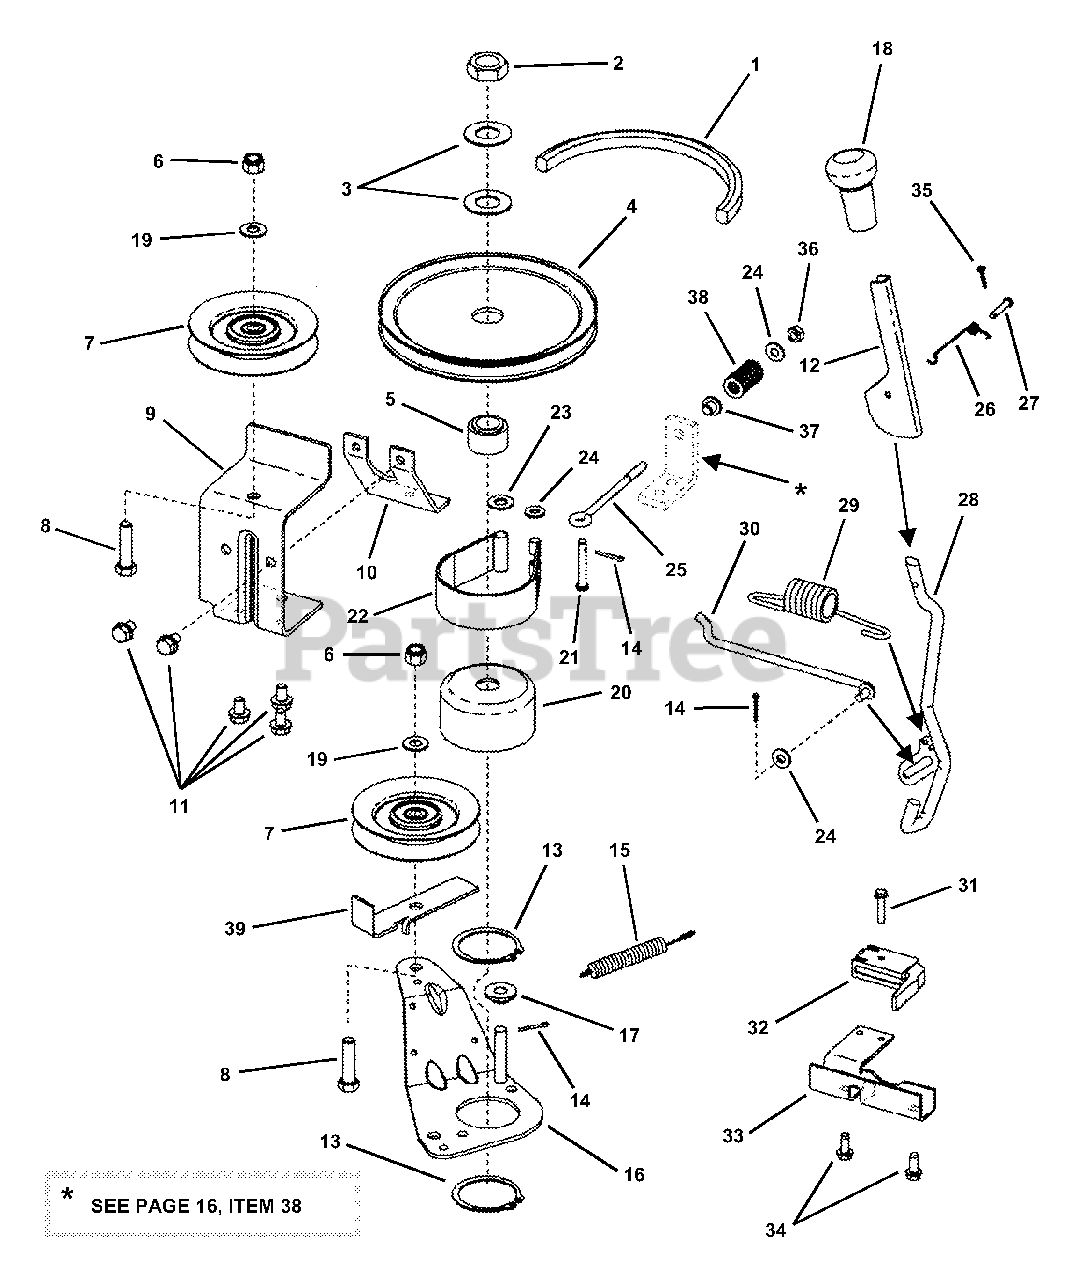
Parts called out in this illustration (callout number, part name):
1	BELT, Drive, (33" Deck) (73.75" AA Section)
2	NUT, 3/4-16 Hex Jam, Grade 8
3	WASHER, 49/64" I.D. x 1-1/2" O.D. Flat
4	PULLEY, Spindle
5	HUB, Pulley
6	NUT, 3/8-16 Nyloc
7	PULLEY, 4" Idler
8	SCREW, 3/8-16 x 1-1/2" Hex Head Cap, Grade 5
9	BRACKET, Fixed Idler (33" Models Only)
10	BRACE, Fixed Idler Bracket (33" Models Only)
11	SCREW, 5/16-18 x 1/2" Hex Washer Self-Tap
12	HANDLE, Blade Engage (Flip)
13	RING, 2" External Retaining
14	PIN, 3/32 x 3/4" Cotter
15	SPRING, Extension, 4" x 1/2" Diameter
16	ARM, Idler (weldment)
17	SPACER
18	GRIP, Handle
19	WASHER, 3/8" Flat
20	DRUM, Brake
21	PIN, 1/4" x 1-5/8" Clevis
22	BAND, Brake
23	WASHER, 3/8" Flat
24	WASHER, 1/4" Flat
25	EYE-BOLT, 1/4-20 x 4"
26	SPRING, Flip Handle
27	PIN, 3/16 x 1" Clevis
28	HANDLE, Blade Lever (ON-OFF)
29	SPRING, Blade Handle
30	ROD, Idler
31	SCREW, #10-32 x 1" Hex Washer
32	SWITCH, Deck Interlock (NO)
33	MOUNT, Handle/Switch
34	SCREW, 1/4-20 x 5/8" Hex Washer Self-Tap
35	PIN, 3/32 x 1/2" Cotter
36	NUT, 1/4-20 Hex Top Lock
37	BUSHING
38	SPRING
39	RESTRICTOR, Belt
